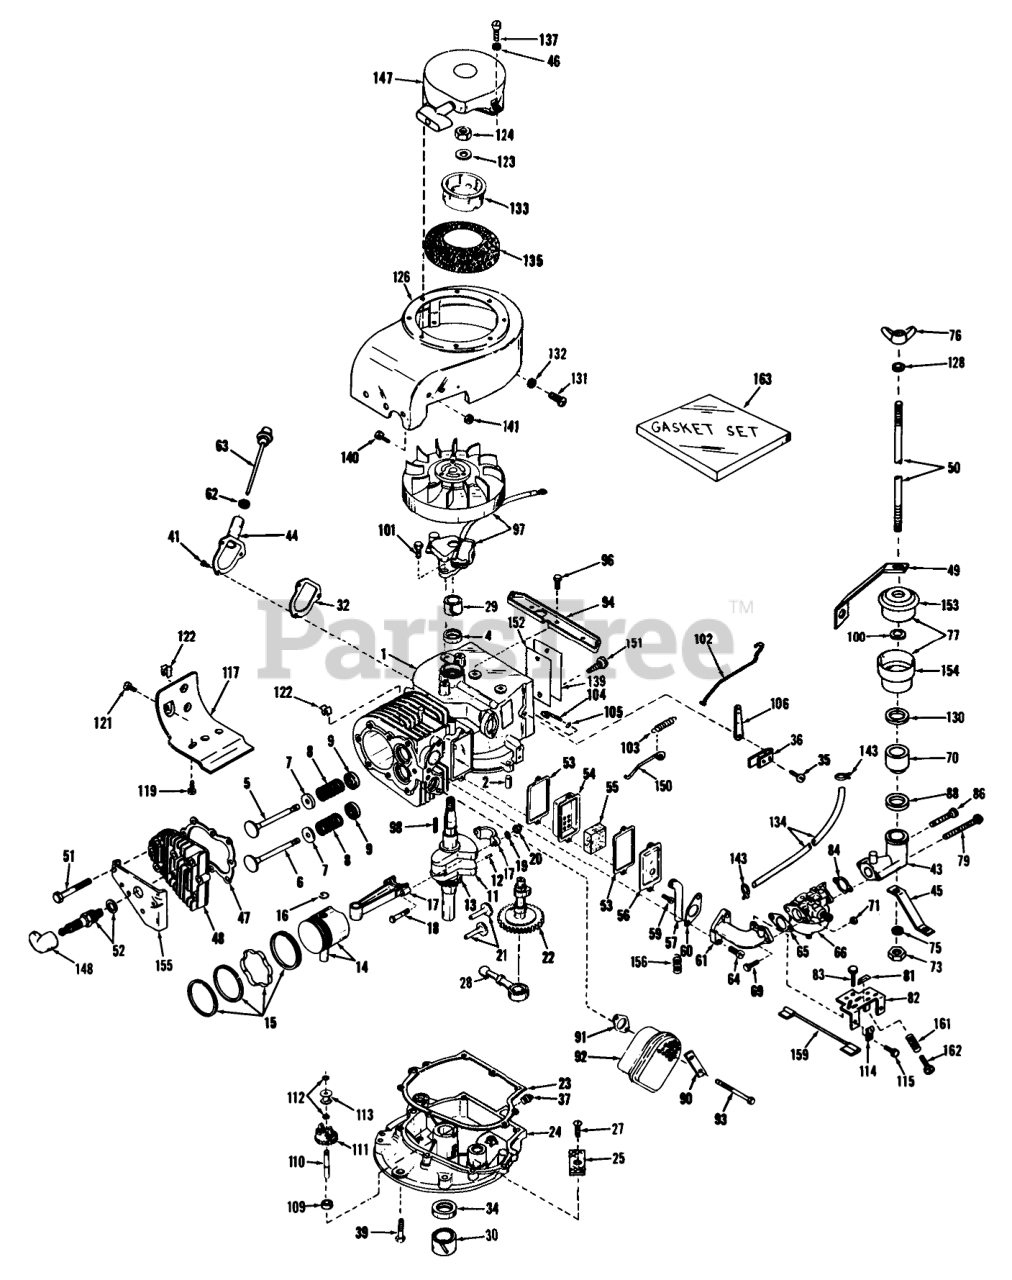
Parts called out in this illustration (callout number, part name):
1	Cylinder Assy. (Incl. Nos. 2, 4, 29 & 32)
2	Pin-Dowel
4	Seal, Oil
5	Valve, Intake (Standard)(Incl. No. 9)
5	Valve, Intake (1/32" Oversize)(Incl. No. 9)
6	Valve, Exhaust (Standard)(Incl. No. 9)
6	Valve, Exhaust (1/32" Oversize)(Incl. No. 9)
7	Cap-Spring, Valve
8	Spring-Valve
9	Keeper-Spring, Valve
11	Crankshaft Assy. (Incl. Nos. 12 & 13)(Model V50-60052G only)
11	Crankshaft Assy. (Incl. Nos. 12 & 13)(Model V60-70073G only)
12	Pin, Groove
13	Gear-Crankshaft
14	Piston & Pin Assy. (Incl. 2 of No. 16)(Standard)
14	Piston & Pin Assy. (.010 Oversize)(Incl. 2 of No. 16)
14	Piston & Pin Assy. (.020 Oversize)(Incl. 2 of No. 16)
15	Clevis Pin
15	Ring Set, Piston (.010 oversize)
15	Ring Set, Piston (.020 oversize)
16	Ring-Retaining, Piston Pin
17	Rod Assy., Connecting (Incl. Nos. 18, 19 & 20)(Model V50-60052G only)
17	Rod Assy., Connecting (Incl. Nos. 18, 19 & 20)(Model V60-70073G only)
18	Bolt, Connecting Rod
21	Lifter Valve
23	Gasket-Cover, Cylinder
24	Flange Assy., Mounting (Incl. Nos. 25, 27, 30, 34, 37 & 110)
25	Screen-Oil Filter
28	Pump, Oil
29	Bushing, Crankshaft
30	Bushing, Crankshaft
32	Gasket, Filler tube
34	Seal-Oil
35	Screw
36	Clamp-Lever, Governor
37	Plug-Drain, Oil (SQH 1/4-18)
39	Screw (1/4-20 x 1-1/4)
43	Elbow, Air cleaner
44	Tube, Oil Filler
45	Brace, Cleaner elbow
47	Gasket-Head, Cylinder
48	CYLINDER HEAD
49	Brace Cleaner
50	Stud, Air cleaner
51	Screw
52	SPARK PLUG
53	Gasket-Breather
54	Body-Breather
55	Element-Breather
56	Cover-Valve
57	Tube-Breather
60	Gasket-Intake
61	Pipe, Intake
62	Gasket
63	Dipstick, Oil (Incl. No. 62)
64	Screw (T-30, 5/16-18x1-3/32)
65	Gasket
66	Carburetor
69	Screw (1/4-28 x 7/8)
70	Spacer, Cleaner
71	Nut and Lock Washer (1/4-28)
73	Nut
75	Lockwasher, Split
76	Nut-Wing
77	Cleaner Assy., Oil Bath Air (Incl. Nos. 100, 128, 130, 153 & 154)
81	Decal
82	Control Assy., Speed
83	Screw (10-24 x 9/16)
84	Gasket
86	KIT - SEAL & WIPER
88	Gasket, Spacer
90	Plate-Locking
91	Gasket Exhaust
92	Muffler
93	Screw
94	Bracket, Blower Housing (Incl. Nos. 131 & 132)
96	Screw (1/4-20x19/32)
98	Key, Flywheel
100	"O" Ring
102	Link Governor
103	Spring Governor
104	Rod, Governor (Incl. No. 105)
105	Washer-Flat
106	Lever-Governor
109	Spacer
110	Shaft, Governor
111	Governor Gear ASM
112	Ring-Retaining
113	Spool-Governor
114	Conduit
115	Screw (10-32 x 3/8)
117	Emnsion, Blower Housing
121	Screw
122	51004 GIL ROTARY TI
123	Washer
126	Housing, Blower
130	1565F GIL TILLER.AD
131	Screw
132	Lockwasher
133	Cup-Starter
134	Line-Fuel
135	Screen, Air
139	480B GIL SNWTHWR O/
141	Nut-Jam (5/16-24)
143	Clamp-Line, Fuel
147	Starter, Rewind
148	Cover-Spark Plug
148	51005 GIL.ROTARY TI
150	Link Governor Spring
152	IDENTIFICATION PLATE
153	Cover, Oil bath cleaner
154	Bowl, Oil Bath Cleaner
155	Cover, Cylinder head
156	Spring, Coil
159	Wire, Ground
161	Spring-Compression
162	Screw
163	Gasket Set
